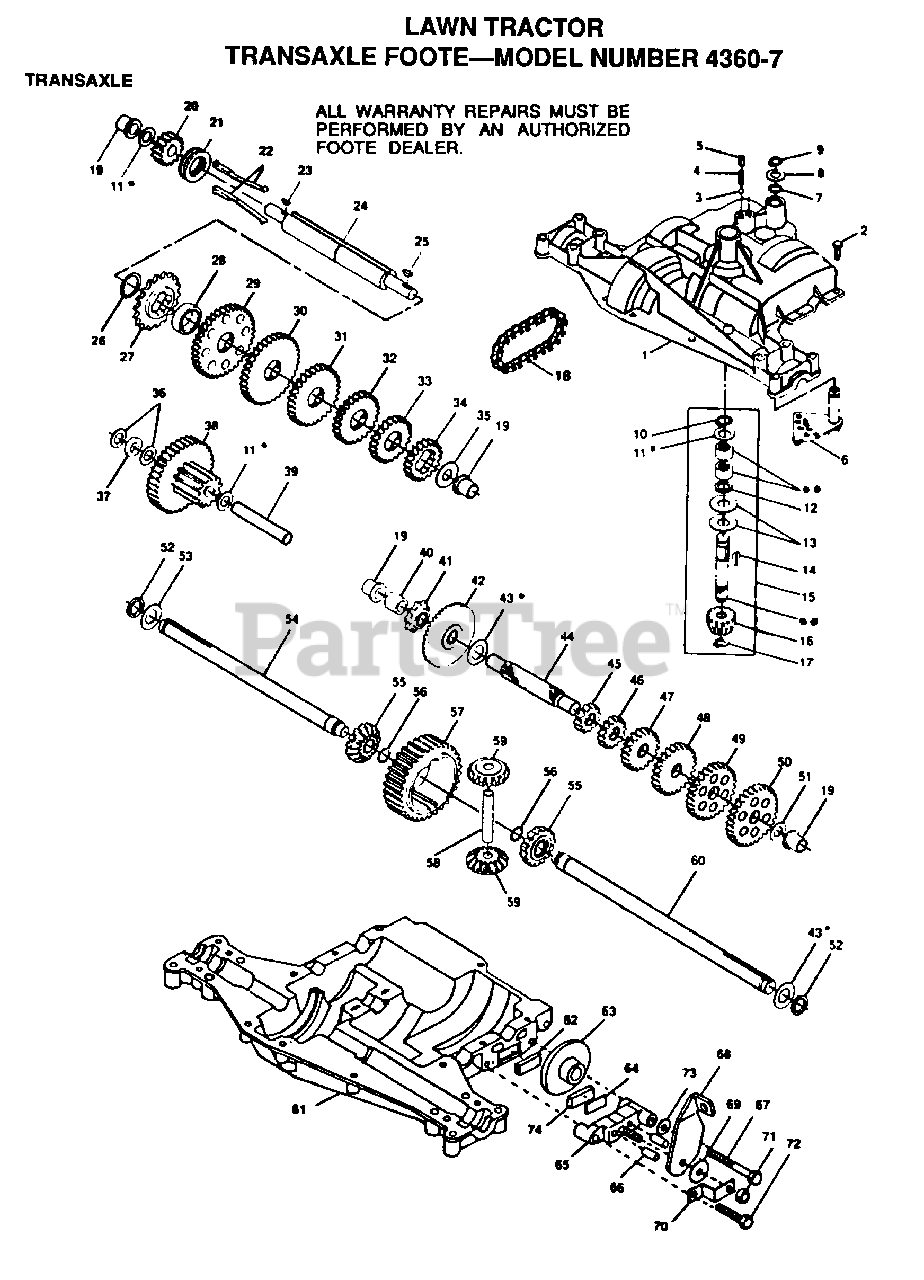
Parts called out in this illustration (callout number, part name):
1	HOUSING UPPER
3	BALL DETENT
4	SPRING, DETENT
5	SCREW, SET
6	ASSY SHIFTER
8	WASHER PLAIN
9	RING RETAINING
10	RING RETAINING
11	WASHER PLAIN
11	WASHER, PLAIN .632 X 1.00 X .026
11	WASHER, PLAIN .632 X 1.00 X .060
13	WASHER, PLAIN .632 X 1.38 X .046
14	KEY WOODRUFF #9
15	ASSY KIT INPUT SHAFT
16	PINION, BEVEL, 14 TEETH
17	RING, RETAINING
18	CHAIN, 24 PITCHES
19	BEARING, FLANGE
20	GEAR SPUR, 14 TEETH
21	COLLAR CLUTCH
22	KEY CLUTCH
23	KEY WOODRUFF #3
24	SHAFT INTERMEDIATE
25	KEY, WOODRUFF, #61
26	RING, RETAINING
27	SPROCKET, 18 TEETH
29	GEAR, SPUR, 37 TEETH
30	GEAR, SPUR, 35 TEETH
31	GEAR, SPUR, 30 TEETH
32	GEAR, SPUR, 25 TEETH
33	GEAR, SPUR, 22 TEETH
35	WASHER, PLAIN .640 X 1.37 X .061
36	WASHER, PLAIN .632 X 1.00 X .026
37	SPACER .630 X 1.00 X .169
38	ASSY GEAR COMB 12&35 TEETH
39	SHAFT IDLER
40	SPACER .635 X .875 X .755
41	SPROCKET, 9 TEETH
42	GEAR, BEVEL, 42 TEETH
43	WASHER PLAIN
43	WASHER, PLAIN .758 X 1.25 X .031
44	SHAFT, DRIVE
45	GEAR, SPUR, 12 TEETH
46	GEAR SPUR, 15 TEETH
47	GEAR, SPUR, 20 TEETH
48	GEAR, SPUR, 25 TEETH
49	GEAR, SPUR, 28 TEETH
50	GEAR, SPUR, 31 TEETH
51	WASHER, PLAIN .632 X 1.00 X .060
53	WASHER PLAIN
54	AXLE LEFT HAND
55	GEAR, MITER, 15 TEETH
56	RING, RETAINING
57	GEAR, SPUR, 32 TEETH
58	SHAFT, CROSS
59	GEAR, MITER, 15 TEETH
60	AXLE, R.H.
61	HOUSING LOWER
62	PUCK, FRICTION
63	DISC, BRAKE
65	JAW, BRAKE
66	PIN, DOWEL
67	SCREW TAPPING
68	LEVER, ACTUATING
69	WASHER, PLAIN .321 X 1.00 X .055
70	BRACKET, ANTI-ROTATION
71	LOCKNUT 5/16-24
72	SCREW TAPPING
73	WASHER PLAIN
74	PUCK, FRICTION
